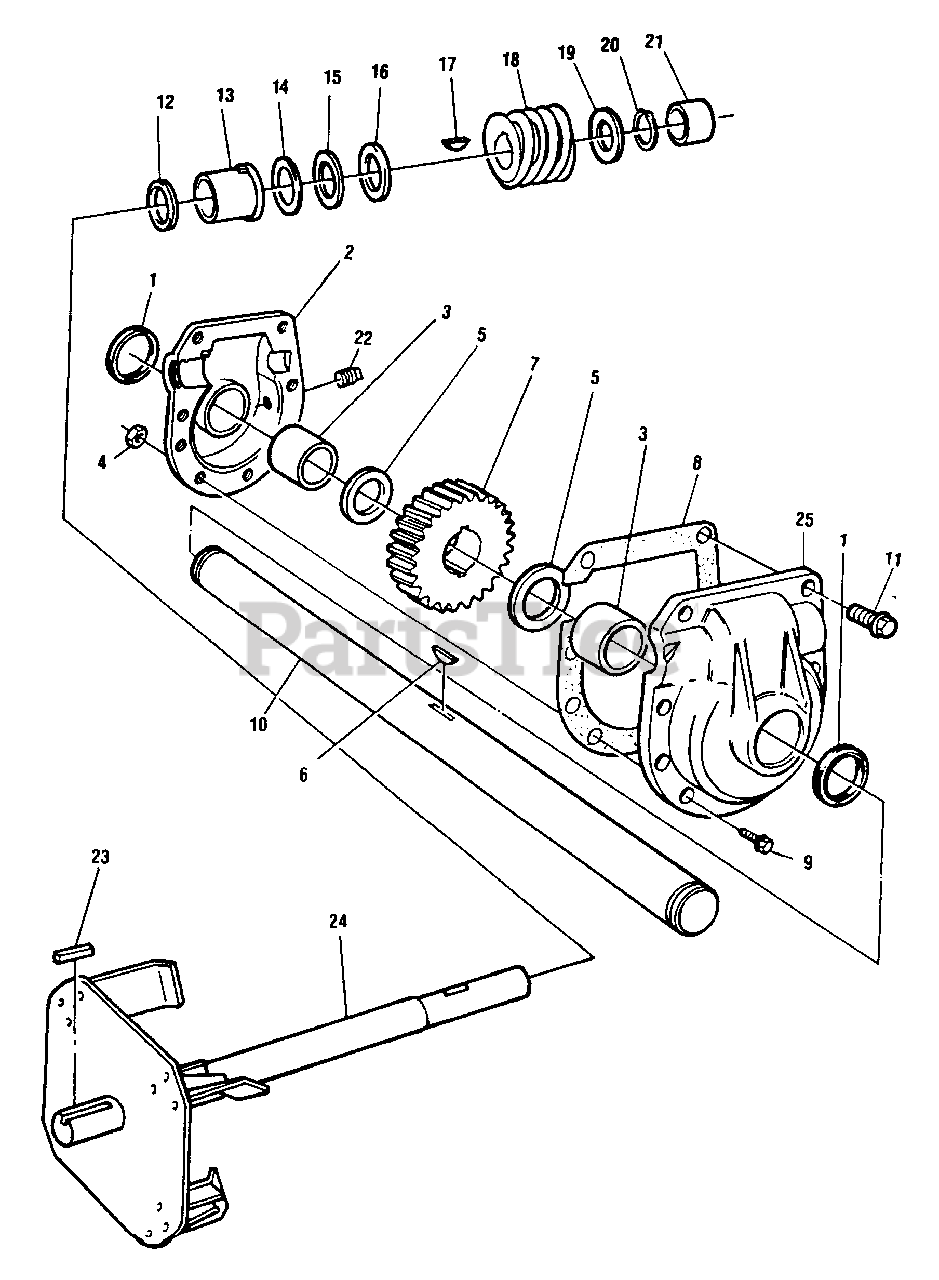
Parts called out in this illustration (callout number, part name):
2	HOUSING - L.H.
4	WASHER - Lock Flange 5/16-24
5	RACE - Thrust
6	KEY - Woodruff #91
7	GEAR - Worm
9	BOLT - 5/16-24 x 1
10	SHAFT - Auger 23"
11	BOLT - 5/16-24 x 1-1/2
12	RING - Quad
13	SHAFT - Bearing Impeller
14	RACE - Thrust
15	BEARING - Needle
16	RACE - Thrust
17	KEY - 3/16"
19	RACE - Thrust
20	RETAINER - Ring
21	SHAFT - Bearing Impeller
22	PLUG - Grease
23	KEY 3/16"
24	IMPELLER SHAFT ASSY.
25	HOUSING - R.H.
